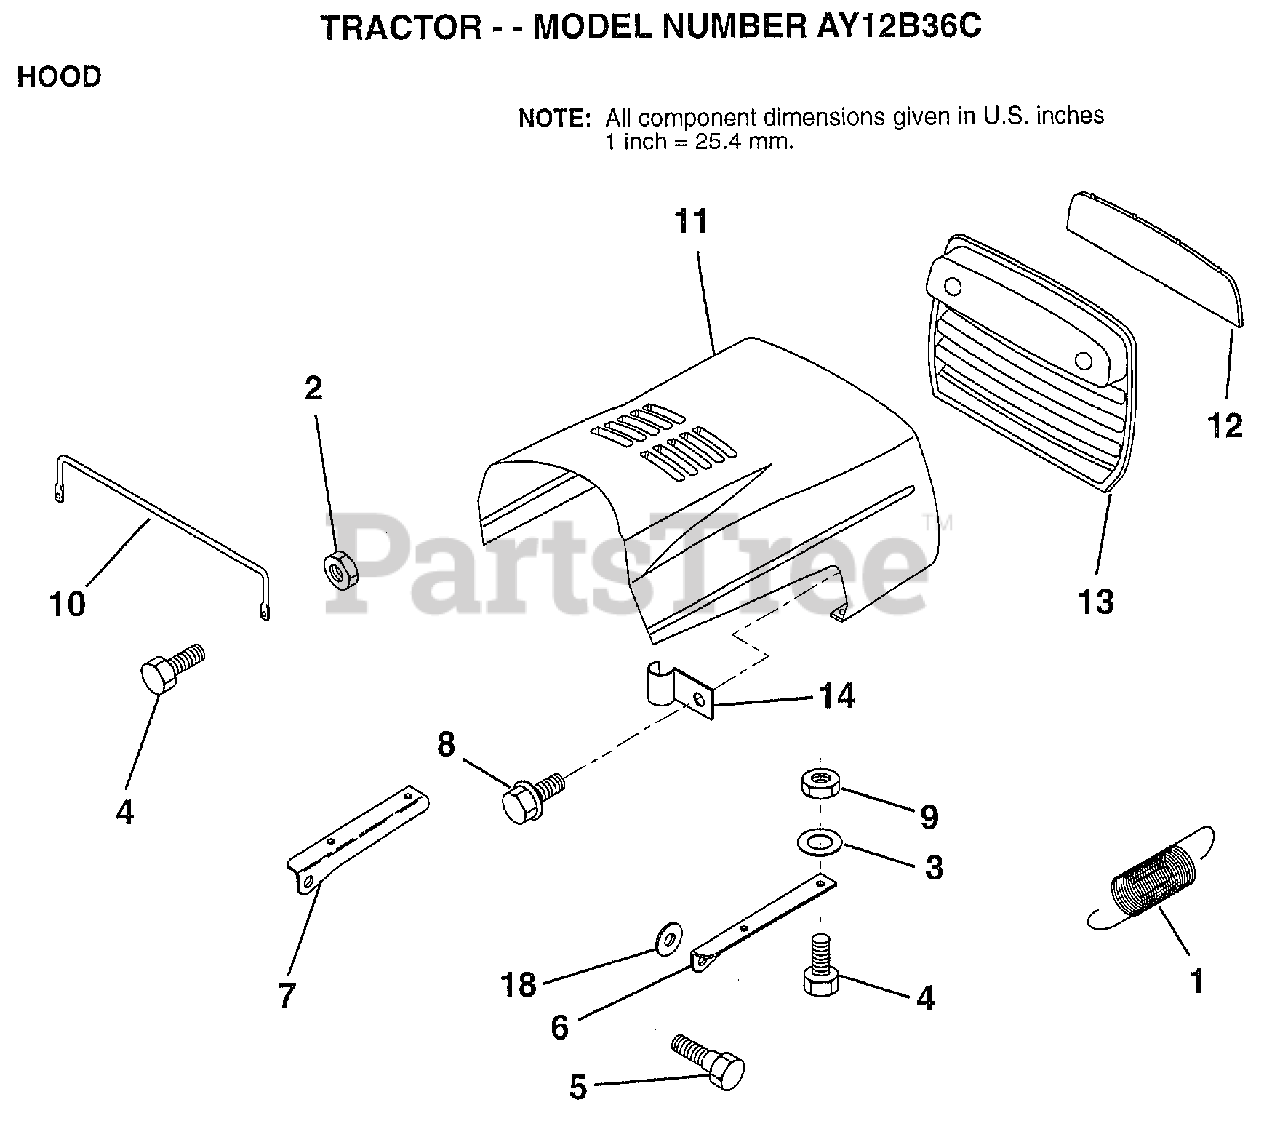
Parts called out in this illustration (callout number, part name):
1	"CASE,BATTERY.MECH"
2	WASHER
3	SCREW
4	SPRING COMPRESSIO
5	PLATE.FEND.LR.ASM
7	PAD FOOTREST
8	SCREW
9	CONSOLE.SHIFT CONTROL
10	PLATE LOCK SHIFT
11	NUT
12	CHASSIS.WELD.ASM.
15	NUT HXKEP 1/4X20
17	DRAWBAR ASM LR
18	"CLIP,INSULATOR"
19	FENDER/FOOTREST
25	SCREW
